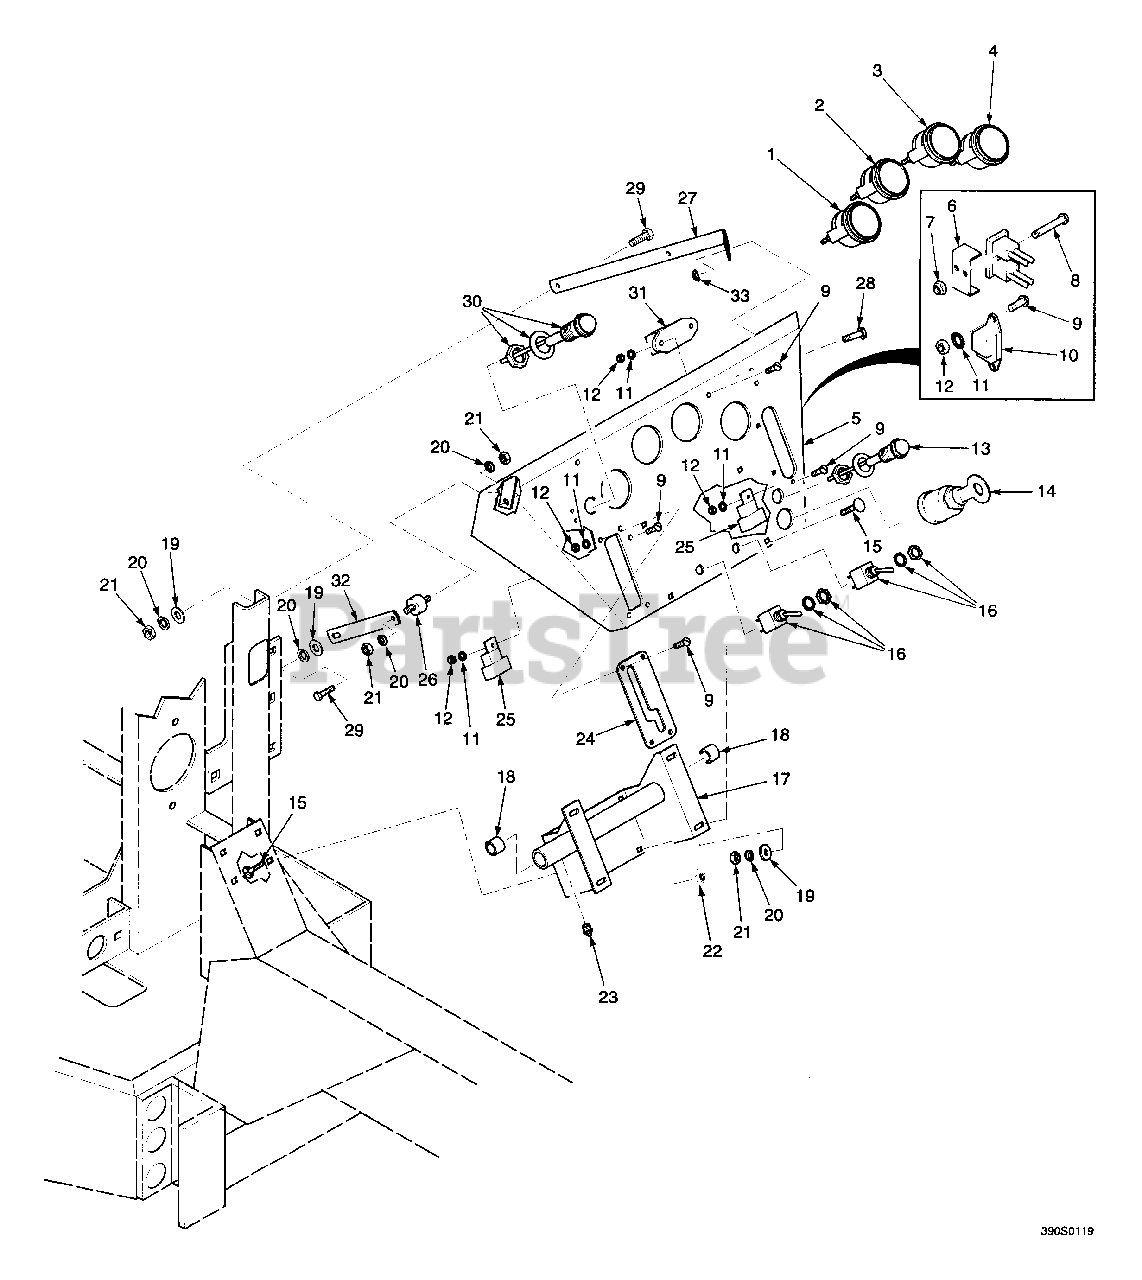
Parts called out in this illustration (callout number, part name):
1	Hourmeter
2	Gauge, Water Temperature
3	Gauge, Fuel Level
4	Voltmeter
5	Instrument Panel with Decal
6	Bracket, Fuse Holder
7	Hex Locknut, Elastic Stop, #10-32
8	Screw, Round Head, #10-32 x 1-1/2
9	Screw, Round Head, #10-32 x 1/2
10	Timer, Glow Plug
11	Lockwasher, External Tooth, #10
12	Hex Nut, #10-32
13	Indicator Light, Glow Plug, Yellow Lens
14	Keyswitch
15	Carriage Bolt, 5/16-18 x 3/4
16	Switch, Deck Lift
17	Mounting Bracket, Instrument Panel
18	Bushing, Oilite - .75 I.D.
19	Flatwasher, 5/16 (.281 x .625 x .065)
20	Lockwasher, 5/16
21	Hex Nut, 5/16-18
22	Serr. Fl. Hex Nut, 5/16-18
23	Grease Fitting
24	Guide, Clutch Lever
25	Relay, Synchronize Start and Cutter Blade
26	Rubber Isolator
27	Brace, Instrument Panel
28	Serr. Flg. Hex Head Capscrew, 5/6-18 x 3/4
29	Bolt, Hex Head, 5/16-18 x 3/4
30	Indicator Light, Oil Pressure, Red Lens
31	Timer, Delay Circuit
32	Bracket, Support Brace
33	Serr. Fl. Hex Nut, 5/16-18
